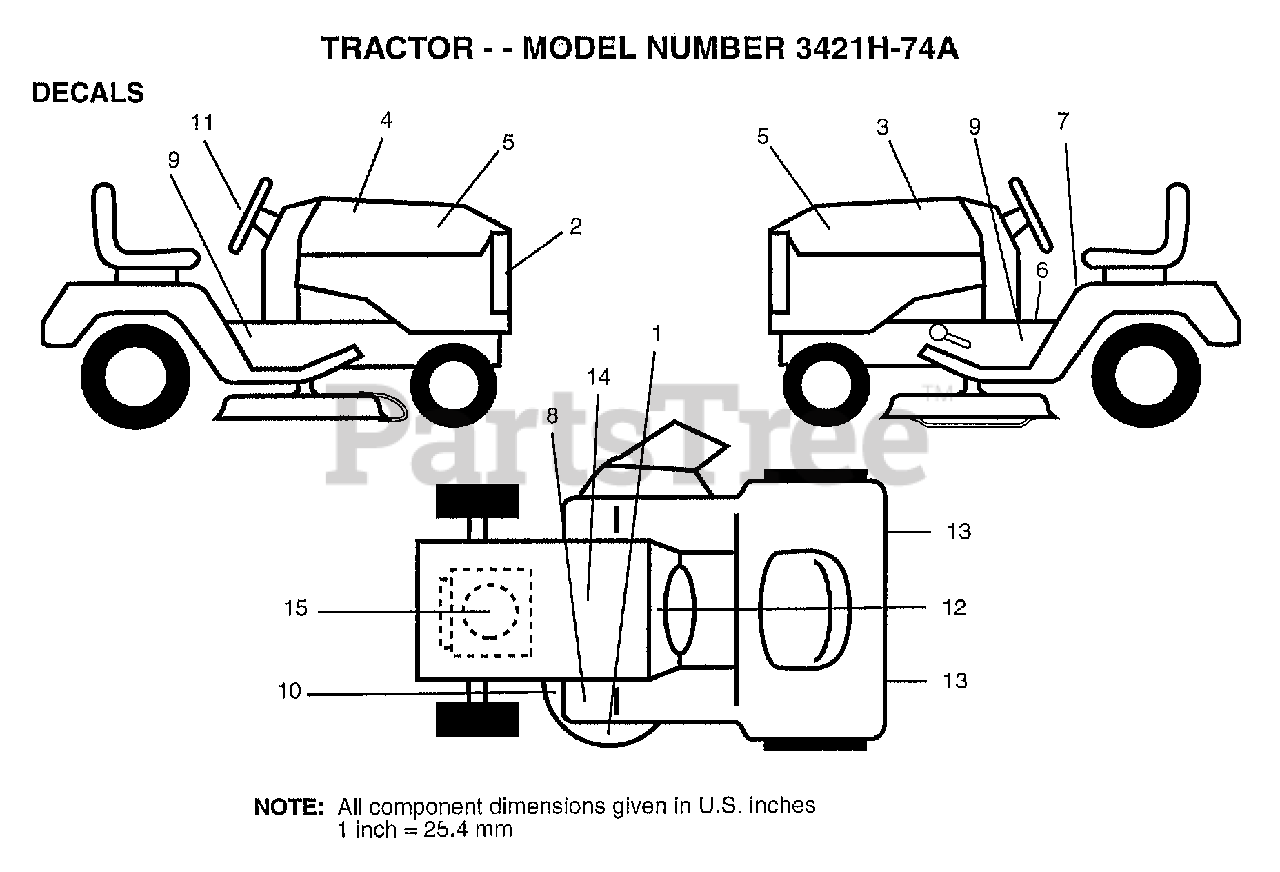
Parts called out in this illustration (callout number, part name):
2	GRILL DECAL
3	"DECAL.HOOD,LH"
4	"DECAL HOOD,RH"
5	NAMEPLATE LOGO
6	DECAL BRAK PARK
7	"DECAL DANGER,FEND"
9	DECAL-CHASSIS
10	DECAL
12	"DECAL-INST,OPER"
13	REFLECTOR-TAIL YT
14	DECAL.BATRY.3-3908
15	DECAL, HP ENGINE
